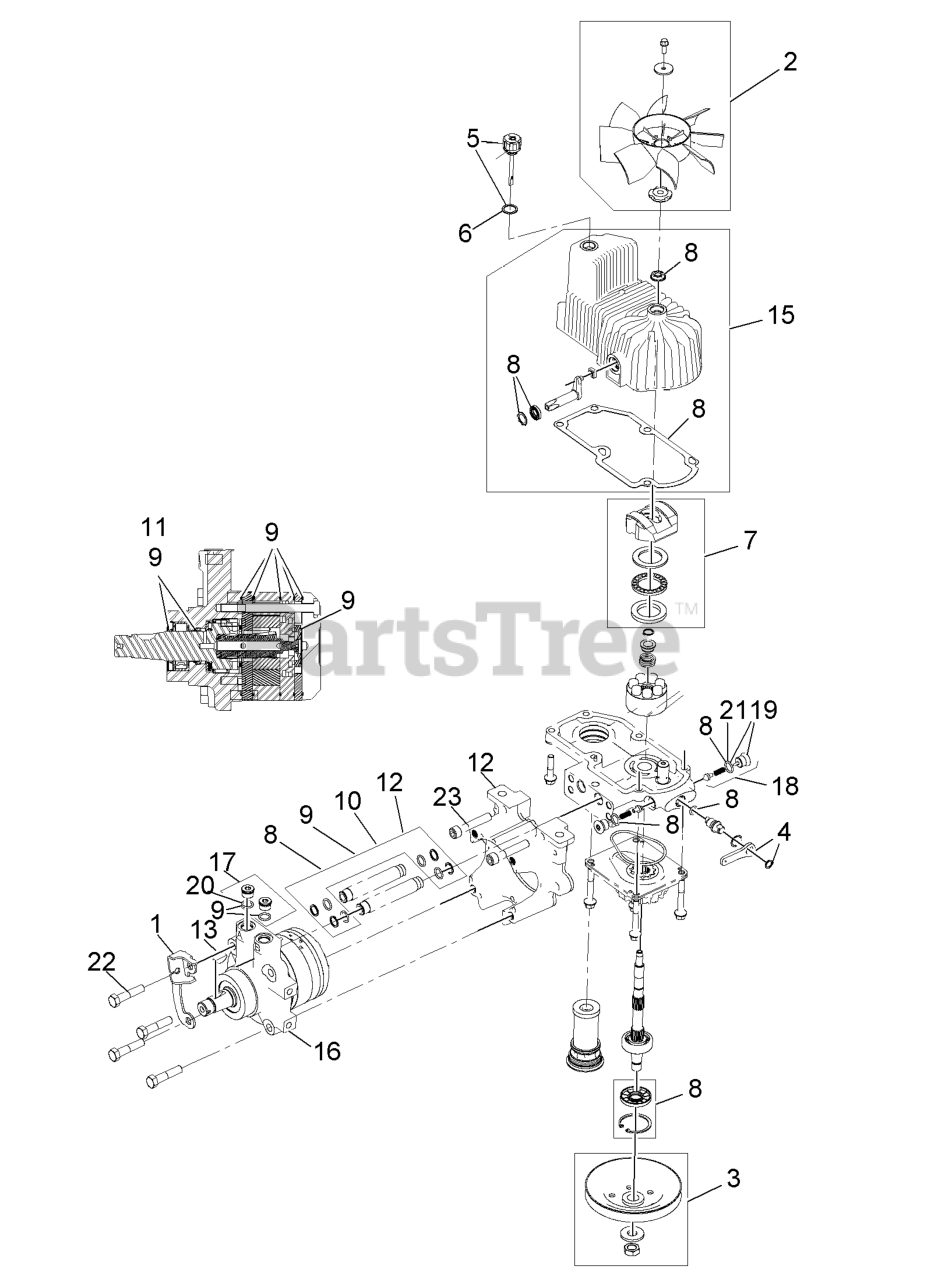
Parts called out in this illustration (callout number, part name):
1	BRACKET-ANCHOR, CABLE
2	FAN KIT
3	PULLEY KIT
4	HANDLE-BYPASS VALVE, HYDRO
5	DIPSTICK-HYDRO W/GASKET
6	GASKET-DIPSTICK, HYDRO
7	SWASH BLOCK KIT
8	PUMP SEAL KIT
9	MOTOR SEAL KIT
10	TUBE SEAL KIT
11	OUTPUT SHAFT SEAL KIT
12	NOSE CUP-UHT
13	KEY-WOODRUFF
15	HOUSING-HYDRO, RH
16	MOTOR-HYDRAULIC RH 240CC
17	MAGNETIC PLUGS SERVICE KIT
18	CHECK VALVE ASM
19	PLUG-CHECK (W/O-RING)
21	O-RING-CHECK VALVE
22	SCREW HH
23	SCREW-HSH
